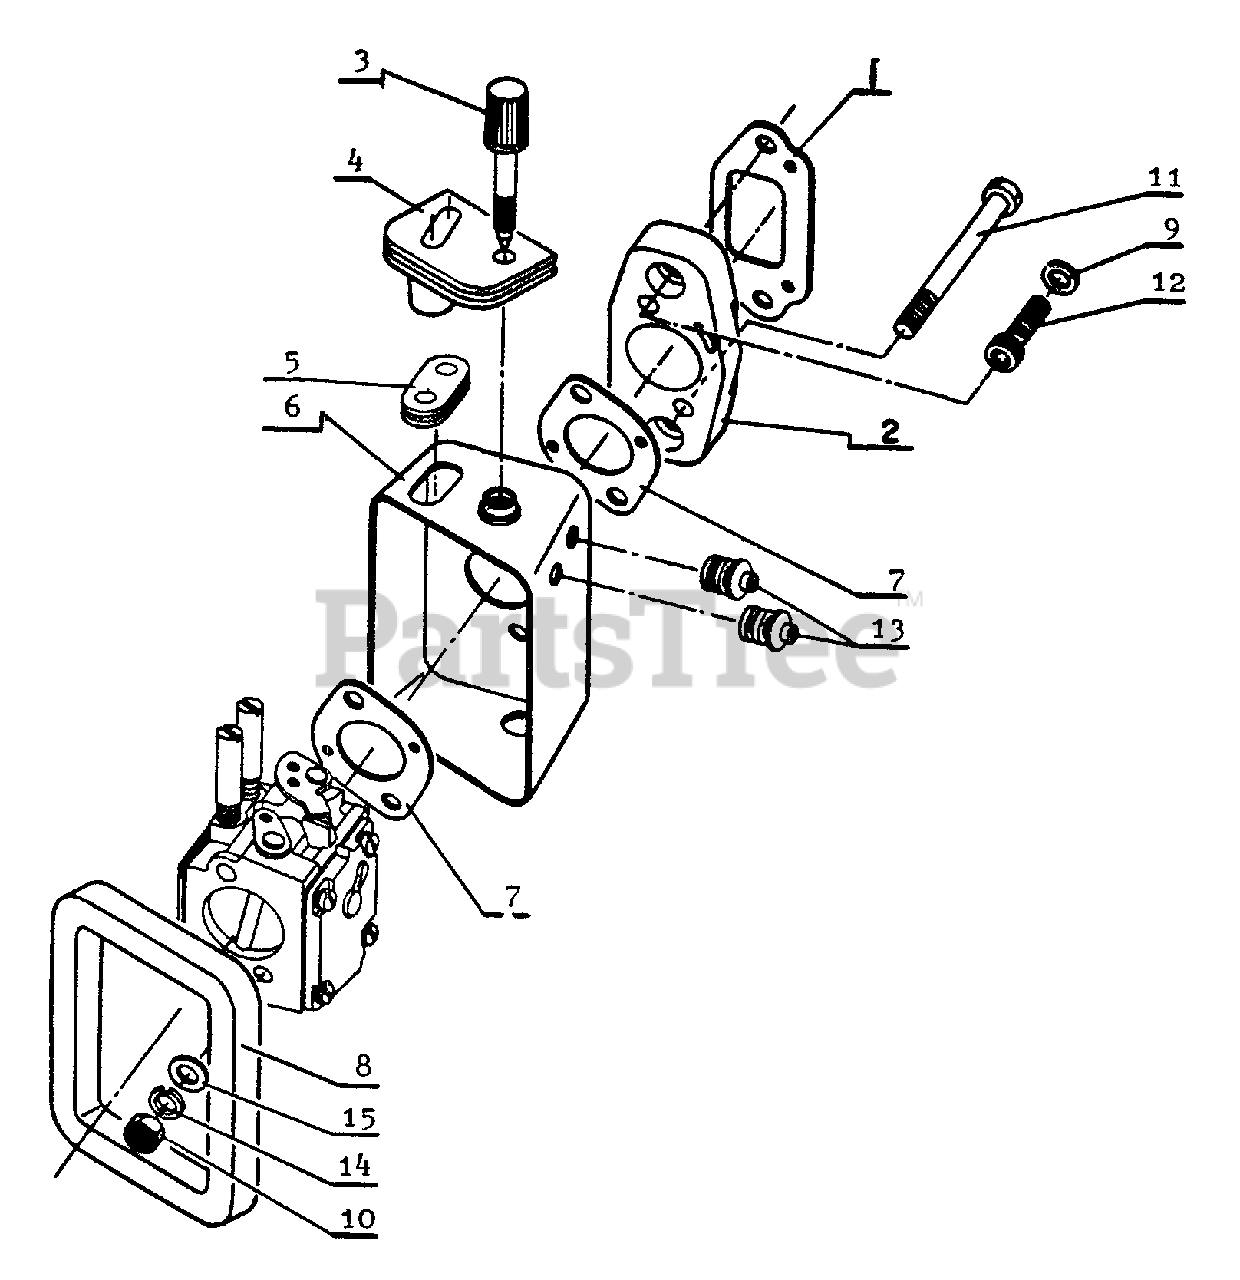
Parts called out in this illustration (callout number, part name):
1	GASKET, INTAKE
2	INSULATOR
3	SCREW, IDLE ADJUST
4	GROMMET
5	GROMMET
6	CASE, CARBURETOR
7	GASKET, INTAKE
8	GASKET, CARBURETOR CASE
9	WASHER
10	LOCKNUT - 5
11	BOLT
12	BOLT 5×25
13	GROMMET
14	WASHER, SPRING 5
15	WASHER 5.2×8×0.8T
